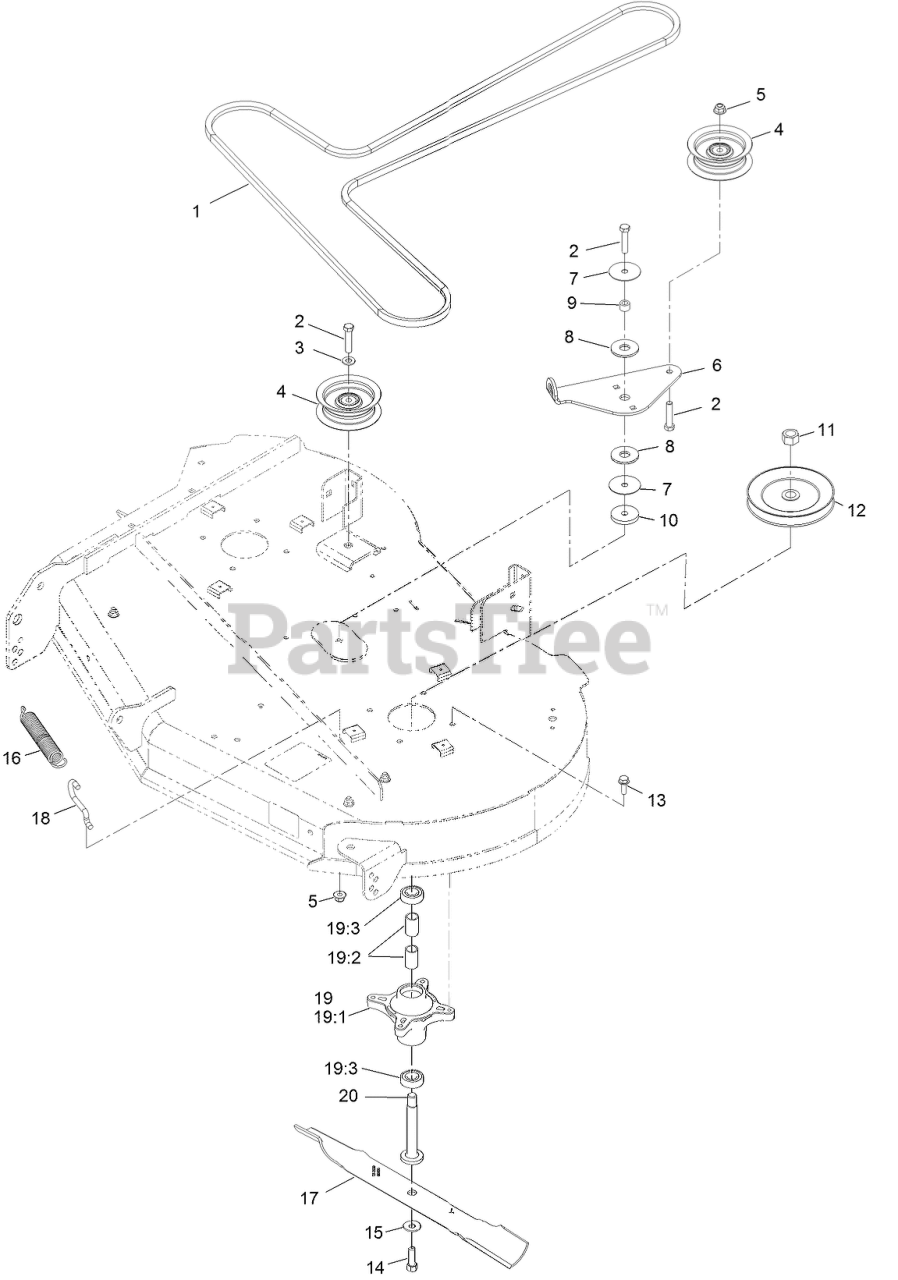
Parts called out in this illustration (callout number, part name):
1	V-BELT
2	SCREW-HH
3	WASHER-FLAT
4	PULLEY-IDLER, FLAT
5	NUT-HF, NI
6	ARM-IDLER
7	WASHER
8	WASHER-FRICTION, COMPOSITE
9	SPACER
10	WASHER-PLAIN
11	NUT-HEX
12	Pulley
13	SCREW-TAPTITE
14	SCREW-HH
15	WASHER-BELLEVILLE
16	SPRING-EXTENSION
17	BLADE-HIGH LIFT
18	HOOK-RETURN, SPRING
19	SPINDLE ASM
19:1	SPINDLE
19:2	SPACER
19:3	BEARING-BALL
20	SHAFT-SPINDLE
